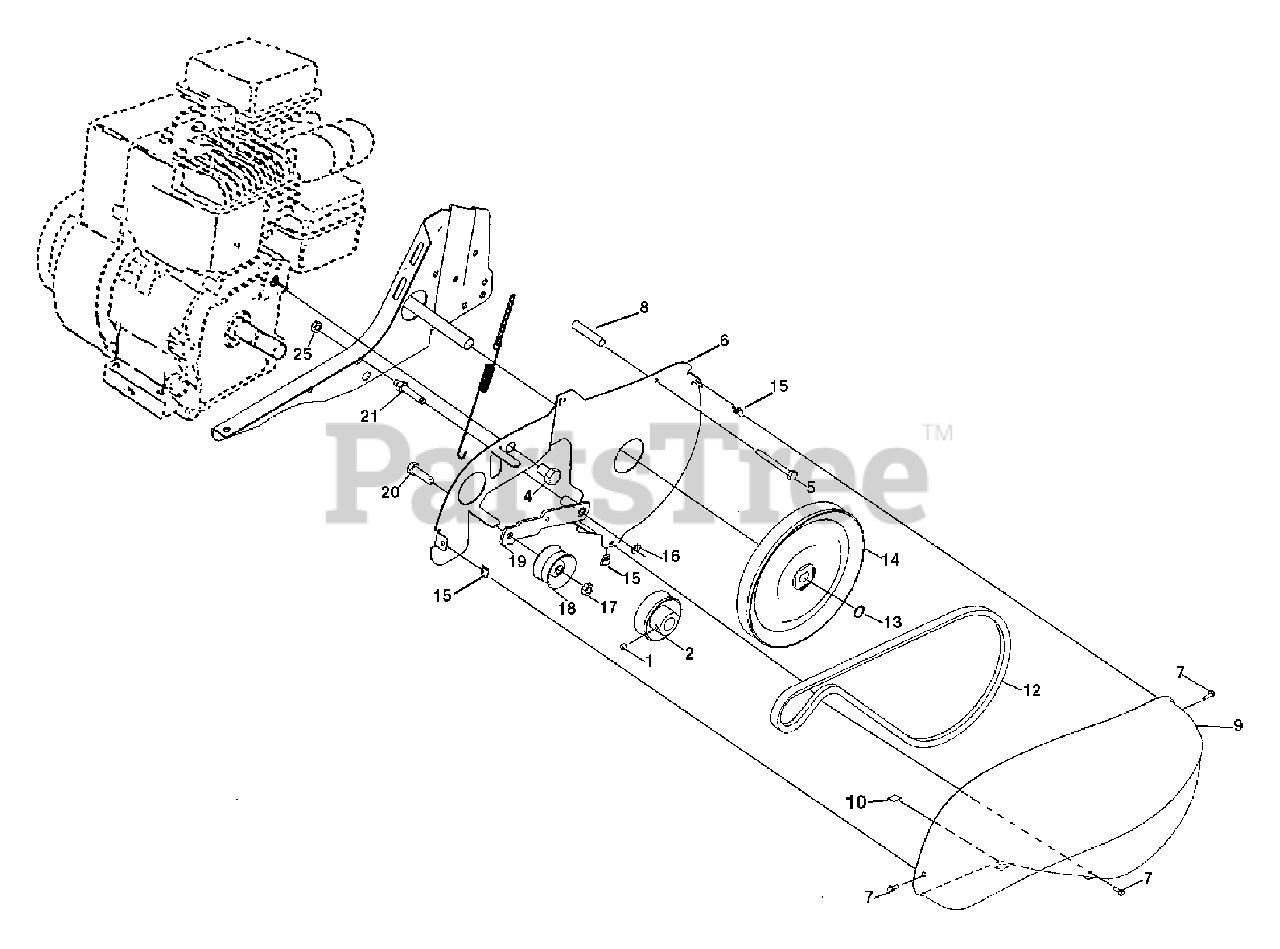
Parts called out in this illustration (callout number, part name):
1	Screw, Set 5/16-18 x 3/8
2	Sheave, Engine
4	Bolt, Hex 1/2-20 x 3/4
5	Bolt Thd Roller 1/4-20 X 2-1/2
6	Shield Inner Guard Belt
7	Screw Hex Wsh Hd #8-18 x 1/2
8	Spacer Split .523 x .718 x 2
9	Guard, Belt
10	Pad, Idler
12	V-Belt Drive
13	Ring, Retainer
14	Sheave, Transmission
15	Nut J Clip #8
16	Ring, Klip
17	Nut, Hex, Jam 3/8-16
18	Pulley, Idler
19	Arm, Idler
20	Bolt, Hex 3/8-16 x 1-1/4
21	Shaft, Idler Arm
25	Nut, Hex, Jam 5/16-18
